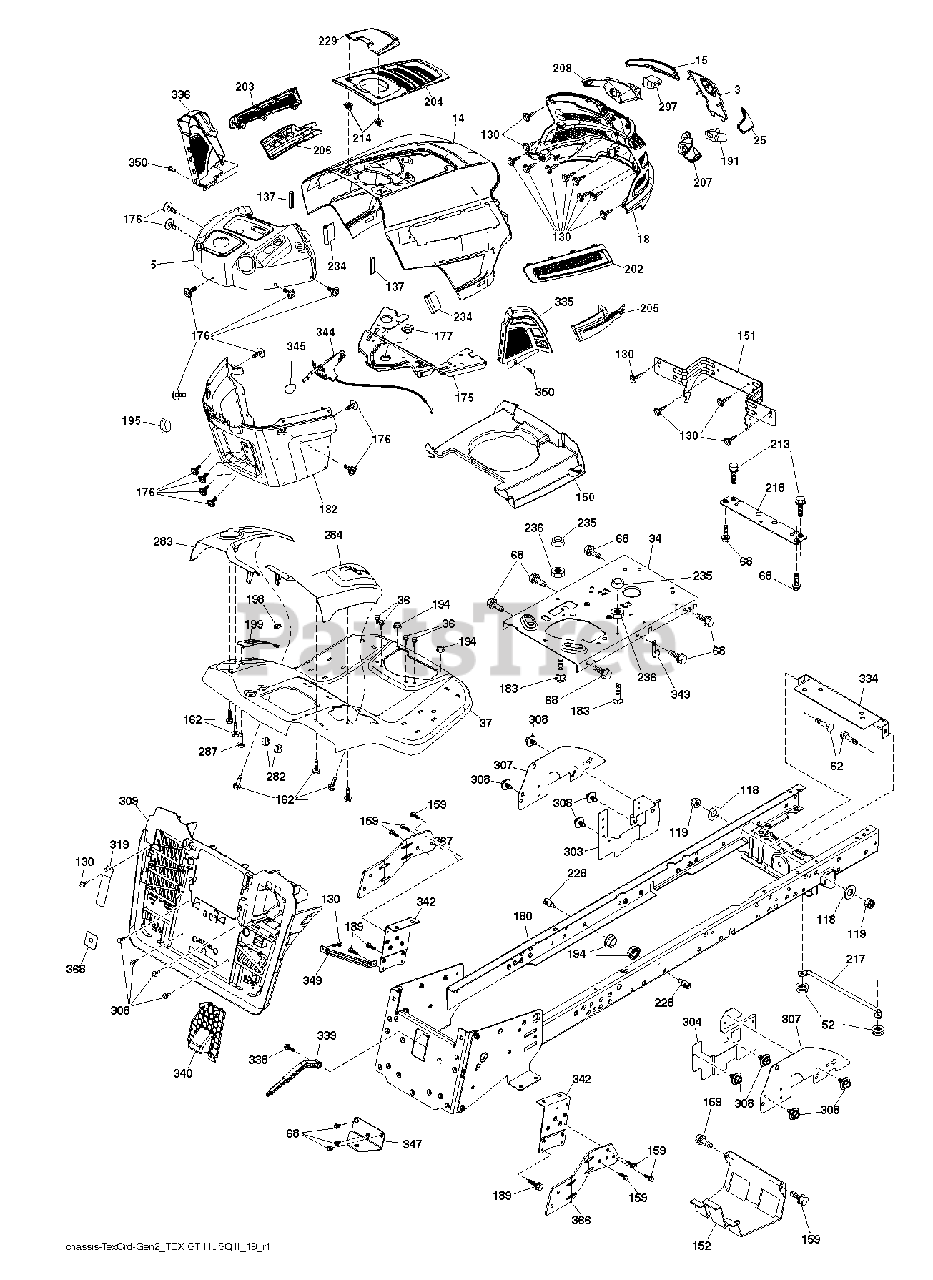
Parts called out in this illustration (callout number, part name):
3	APPLIQUE.SUBASM.GT.HUSQ.II
5	GT2.DASH.UPPER.W/BUMPERS
14	HOOD.ASM.HUSQVARNA.GT.TEX.ORAN
15	LED LIGHT.LH
18	GRILLE.SUBSTRATE.2011.
25	LENS.RH
34	PLATE.ENGINE.10GA.CRD.GENII
36	SCREW 5/16"
37	FENDER.TEX.SRD.CRD.FRN.GUARDS
52	LOCKNUT
62	BOLT D
68	SCREW LT
118	WASHER
130	SCREW.#10 X 0.750.BOS
137	BUMPER DASH
150	AIR.DUCT.GTV.BLACK
151	BRACKET.PIVOT.HOOD.GT.HUSQ.II
152	SHIELD.BROWNING.PNT.GT.V2
159	SCREW, 3/8-16X3/4
162	SCREW.HI-LO.CONSOLE
175	PLATE.CROSSMEMBER.HUSQ
176	SCREW.#10-24X5/8.RN.QU
177	BUSHING, STEERING
180	WELDMENT.CHASSIS.TEX.CRD.GEN.2
182	DASH DASH LOWER
183	BOLT.5/16-18X1-1/4 FULL THD
189	SCREW
191	INSERT INFLECT.RH
194	NUT LOCK HEX FLANGE 5/16-18
195	PLUG.HOLE.DASH.LOWER.12V.BLK
198	INDICATOR.DECK.LIFT.RED
199	PLATE DECK LIFT
202	VENT.SIDE.RH.GT.HUSQ.II.
203	VENT.SIDE.LH.GT.HUSQ.II.498
204	VENT.TOP.EXTERNAL.FILL.GT2.GRE
205	SIDE.TRIM.RH.GT.HUSQ.II
206	SIDE.TRIM.LH.GT.HUSQ.II.GRAY
207	LIGHT.BEZEL. RH
208	LIGHT.BEZEL.LH
213	BOLT
214	CLIP.RETAINER.TINNER.
217	ROD.PIVOT.HOOD
218	X-PIECE.HOOD.STOP.NON/
228	STUD.FASTNER.W/ANTI-ROTATE
229	LID.EXT.FILL.GT.HUSQ2.BLACK
234	BUMPER.HOOD.TEX.HUSQVARNA
235	SPACER FENDER
236	NUT.CENTERLOCK.5/16-
282	CLIP.RETAINER.CONSOLE.LT.HUSQ
283	CONSOLE.DECKLIFT.CRDII.498
284	CONSOLE.PEDAL.HYDRO
287	SCREW 1/4X20
297	INSERT REFECT LH
303	SHIELD.LWR.LH.LT.30"CRDSRD.PNT
304	SHIELD.LWR.RH.LT30DECK.PNT.BLK
307	SHIELD.UPPER.CRD.SRD.ISO
308	BOLT, 5/16-18 X 1 3/4
309	BACKPLATE.ASM.CRDII.ANTIROTAT
319	LEVER.BAG.CRDII.ANTIROTATION
334	BRACKET.ENGINE
335	COVER.LOWER.DASH.RH.BLACK
336	COVER-LH.LOWER.DASH.GT2.BLACK
338	BOLT BOLT SHOULDER
339	LEVER LEVER BAGGER
340	BATTERY.DOOR.TEX.CRD.GEN.2,1
342	SUPPORT SUPPORT FENDER
343	CLIP CLIP
344	CONTROL.EZ.MULCH.TEX/CRD
345	RP KNOB.OVAL.TAPERED.3/8-16BLK
347	HITCH HITCH TOW TEX CRD GEN 2
349	BRACKET.SUPPORT.LRVB/CRD
350	CLIP.X-MAS.TREE
366	BRACKET.RH.FRONT.BAGGER.BLACK
367	BRACKET.LH.FRONT.BAGGER.BLACK
368	FULL.LEVER.BAGGER.TEX.CRD
